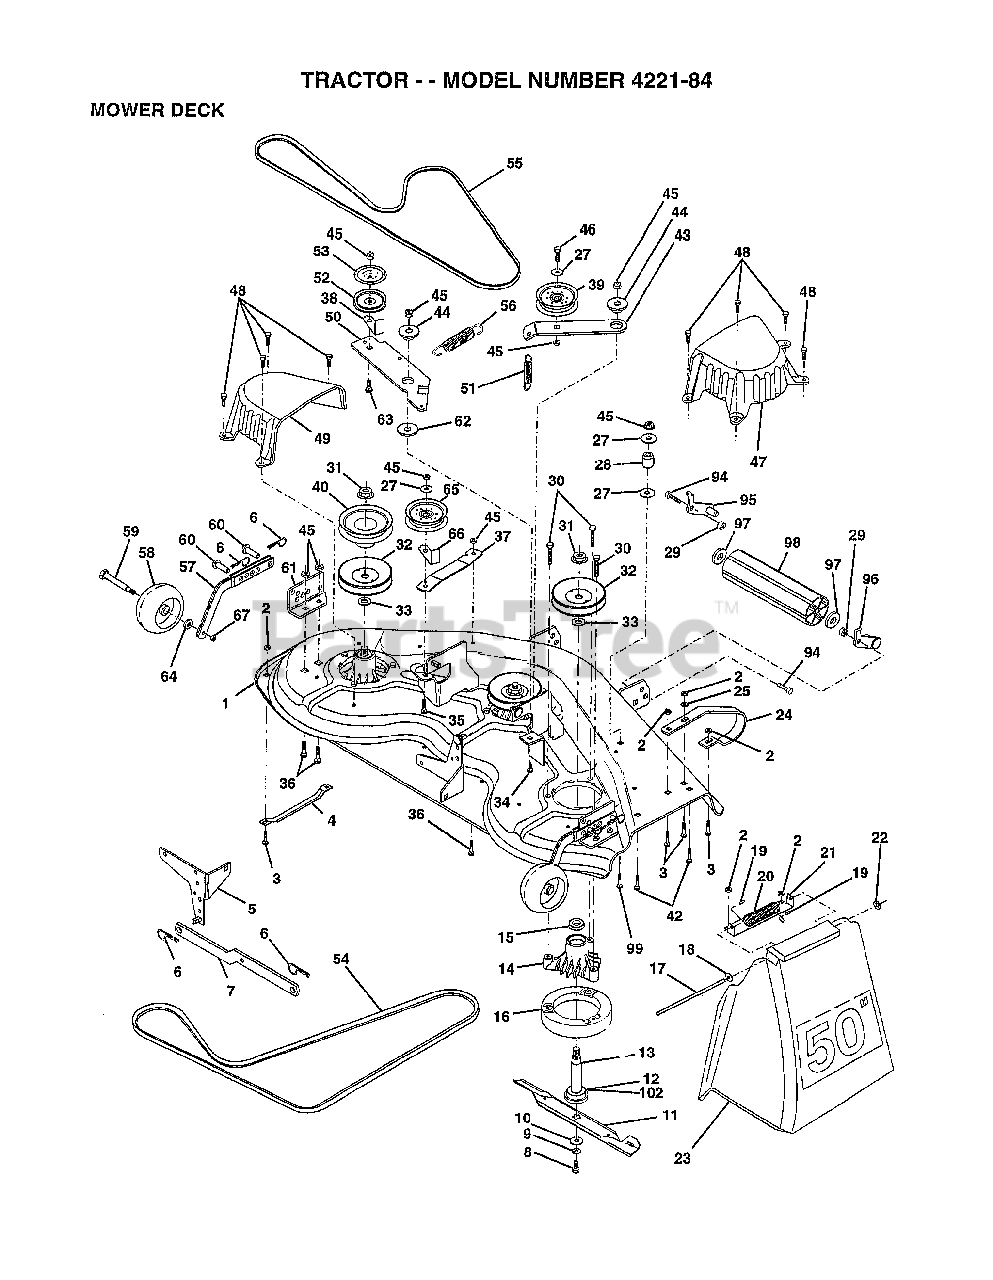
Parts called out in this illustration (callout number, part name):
1	"DECK ASM-50"""
4	RUNNER-LH M
5	BRKT.ASM.SW.44/50
8	BLADE BOLT
10	WASHER.HARD.BLADE
11	"BLADE.50"" HD"
12	BEARING.BALL
13	SHAFT.ASM.W/BRNG
14	HOUSING.MAND.44.V
15	BEARING
16	STRIPPER RND MWR
17	ROD-HINGE T
18	WASHER
19	CAP-SLEEVE LT
20	SPRING TORSION
21	BRKT DEFLECTOR
23	DEFLECTOR
24	"RUNNER RH 50"" DK"
25	WASHER M
27	WASHER
29	NUT
30	"SCREW-THD ROLL,WA"
32	PULLEY.MANDREL.42
33	WASHER
34	BOLT.3/8-14X1.25
35	BOLT
36	BOLT D
37	STIFFENER.ARM.IDL
38	"KEEPER-BELT,IDLER"
39	FLAT IDLER PULLEY
40	"PULLEY.DRIVEN.44"""
42	BOLT
43	"ARM.IDLER.SEC.44"""
44	SPACER RETAINER
47	"COVER.MAND.RH.44"""
48	SCREW.1/4-20X5/8
49	COVER.MANDREL.LH
50	ARM.IDLER.PRIMARY
51	"SPRING.SEC.44""VEN"
52	PULLEY.IDLER.VGRO
53	SHIELD.IDLER.44.V
54	BELT V PRIM 50
55	BELT-V.SEC.46.KEL
56	SPRING.EXT.DECK.
57	BAR.ASM.GUAGE.WHL
58	WHEEL.GUAGE.MED.
59	BOLT.SHOULDER
60	PIN.CLEVIS
61	BRACKET.GUAGE.WHL
62	HARDENED WASHER
63	BOLT.3/8-16X1.50
64	WASHER
65	PULLEY IDELR FLAT
66	"KEEPER-BELT,IDLER"
67	LOCKNUT
94	BOLT
97	WASHER
99	BOLT
102	WASHER.FELT.
